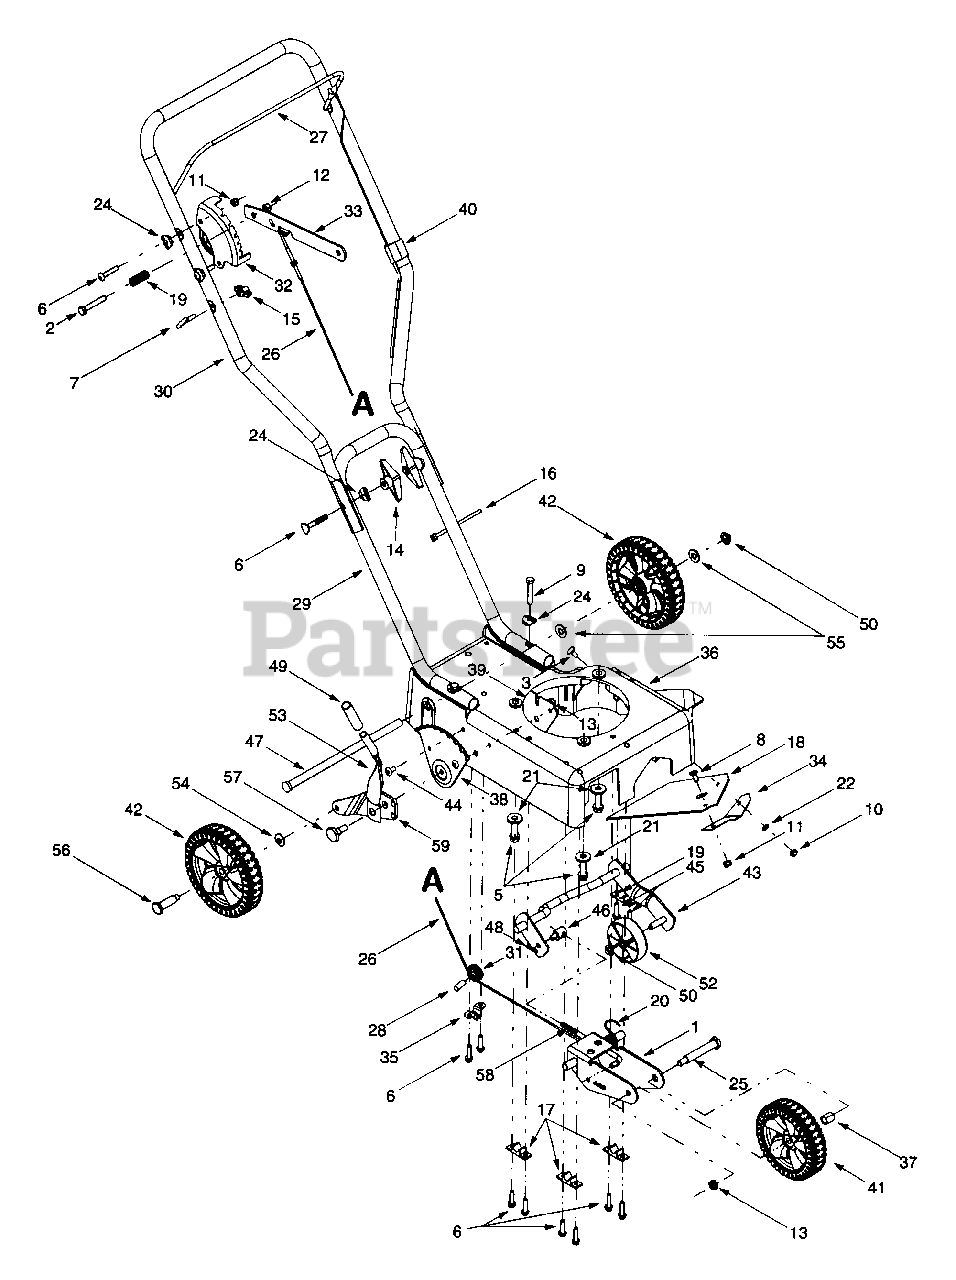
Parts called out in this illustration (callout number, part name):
1	Front Wheel Bracket Assembly
2	Hex Cap Screw, 5/16-18 x 2.0
3	Carriage Screw, 1/4-20 x .625
5	Sems Screw, 3/8-16 x 1.5
6	Carriage Bolt, 5/16-18 x 2.0
7	Eye Bolt (Rope Guide), 1/4-20
8	Hex Cap Screw, 1/4-20 x .5
9	Hex Cap Screw, 5/16-18 x 1.75
10	Hex Nut, 1/4-20
11	Hex Lock Nut, 1/4-20
12	Hex Lock Nut, 5/16-18
13	Jam Lock Nut, 3/8-16
14	Wing Knob, 5/16-18
15	Wing Knob, 1/4-20
16	Cable Tie
17	Block Bushing, .515 x .62
18	Discharge Deflector Shield
19	Compression Spring, .55 x 1.37
20	LH Torsion Spring, .655
21	Flat Washer, .385 x 1.0 x .135
22	Lock Washer, 1/4
24	Saddle Washer, .320 x .93
25	Shoulder Screw, 3/8-16, .5 x 2.62
26	Depth Index Cable, 44.5"
28	Cable Roller Rod
32	Depth Index Bracket
34	Discharge Deflector Keeper
37	Sleeve Spacer, .520 x .860
38	Curb Wheel Adjuster Plate
39	Curb Wheel Back Plate
40	Control Cable w/ Clip, 31.75"
41	Bar Tread Wheel, 7 x 1.8
42	Bar Tread Wheel, 8 x 1.8
45	Hi-Lo Tap Screw, 1/4-15 x 1.0
46	Ferrule, 5/16-24 s .312
47	Curb Axle
48	Internal Cotter Pin
49	Height Adjuster Grip, 2.5"
50	Push Cap, 3/8
52	Curb Support Roller
53	Height Adjuster Spring Lever
54	Bell Washer, .401 x .870 x .063
55	Flat Washer, .510 x 1.0 x .125
56	Shoulder Screw, 3/8-16, .49 x 1.4
57	Shoulder Screw, .50 x .434
58	Link Rod, 5/16-24
59	Curb Wheel Pivot Arm
